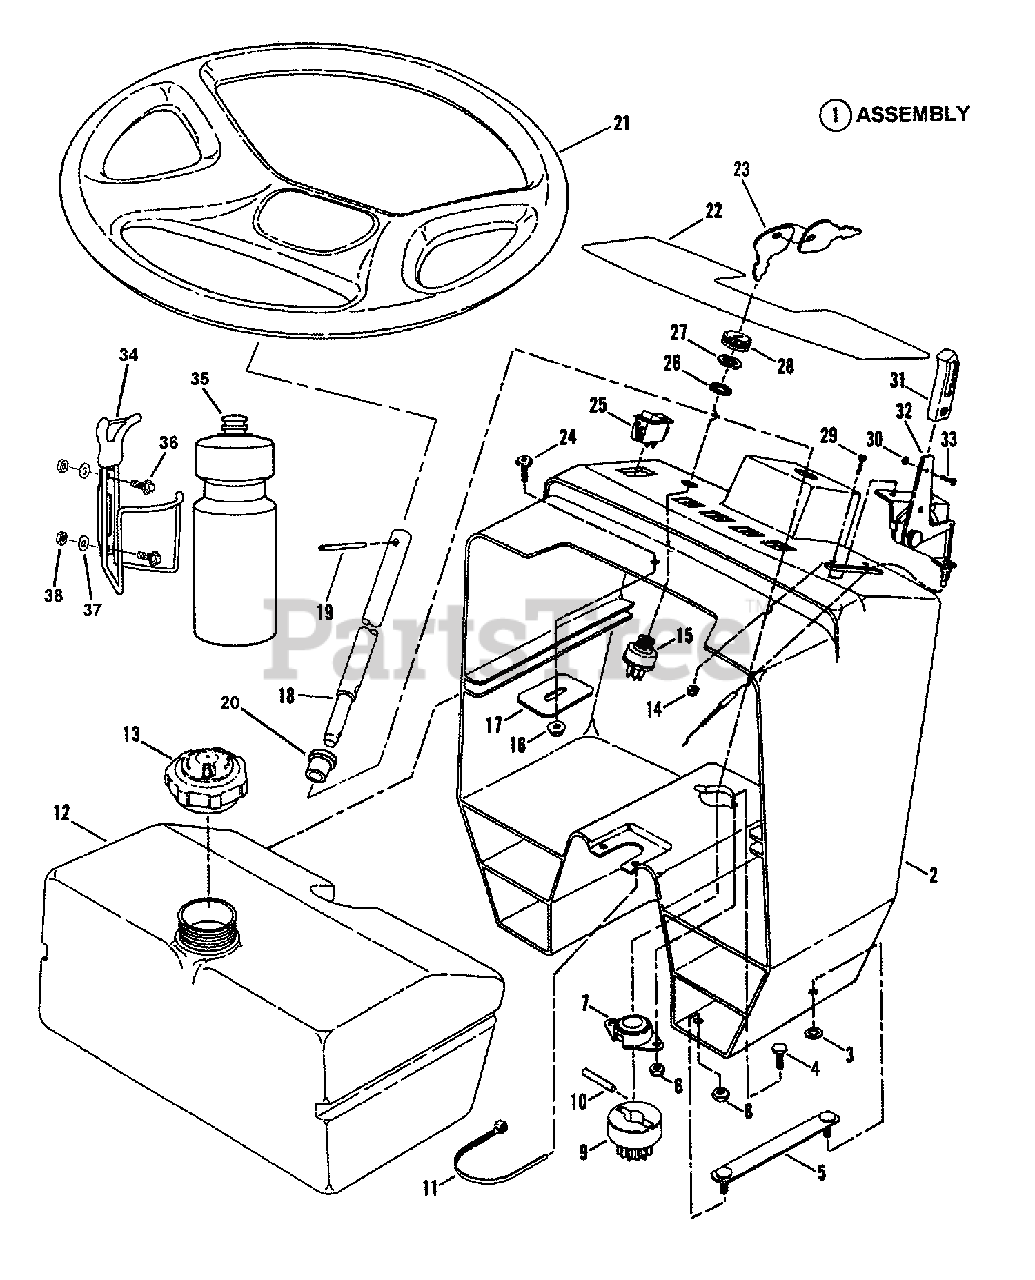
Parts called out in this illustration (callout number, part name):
1	ASSEMBLY, Console (Includes items 2 thru 7)
2	CONSOLE, OPPLT-Electric Clutch
3	RETAINER, 5/16" Bolt
4	SCREW, 1/4-20 x 3/4" Hex Head Cap, GR 5
5	ASSEMBLY, Strap-Clinch Stud
6	NUT, 1/4-20 Hex Nyloc
7	ASSEMBLY, BEARING, Flange .75 I.D. PM
8	NUT, 5/16-18 Hex Center Lock, GR 5 or B
9	GEAR, Pinion, Steering Shaft
10	PIN, Dowel, 1/4 x 1-1/4"
11	WIRE TIE, 1.29 long Black
12	ASSEMBLY, Fuel Tank/Cap 8-QT (Incl. item 13)
13	CAP, Fuel Tank
14	NUT, #10-24 Hex Nyloc
15	SWITCH, Ignition-Afterfire Solenoid (Incl. item 27)
16	NUT, 5/16-18 Hex Large Flange Center Lock
17	BRACKET, Hood Latch Catch
18	SHAFT, Steering
19	PIN, .26 x 2-1/4" Spiral
20	BEARING, .750 I.D.
21	STEERING WHEEL, Kelch Vector
22	DECAL, Console
22	DECAL, Console Basic
23	KEY, Pair
24	SCREW, 5/16-18 x 5/8" Truss Head (Torx)
25	LIGHT SWITCH, Rocker SPST
26	SPACER, .65 x .88 x .10
27	NUT, 5/8-32 Hex
28	BEZEL
29	SCREW, #10-24 x 5/8" Flat Head Cross Countersunk Machine
30	NUT, #8-32 Hex, GR 2 or B
31	LEVER, Throttle Control
32	* CONTROL, Throttle (conduit length: 44.60")
32	CONTROL, Throttle (conduit length: 47.60")
33	SCREW, #8-32 x 3/8" Cross-Recessed, Fillester Head, GR 2
34	HOLDER, BOTTLE (wire)
35	BOTTLE, Water
36	SCREW, #10-24 x 5/8" Hex Washer Self-Tap
37	WASHER, .219 x .500 x .049 Flat
38	NUT, #10-24 Hex Nyloc
